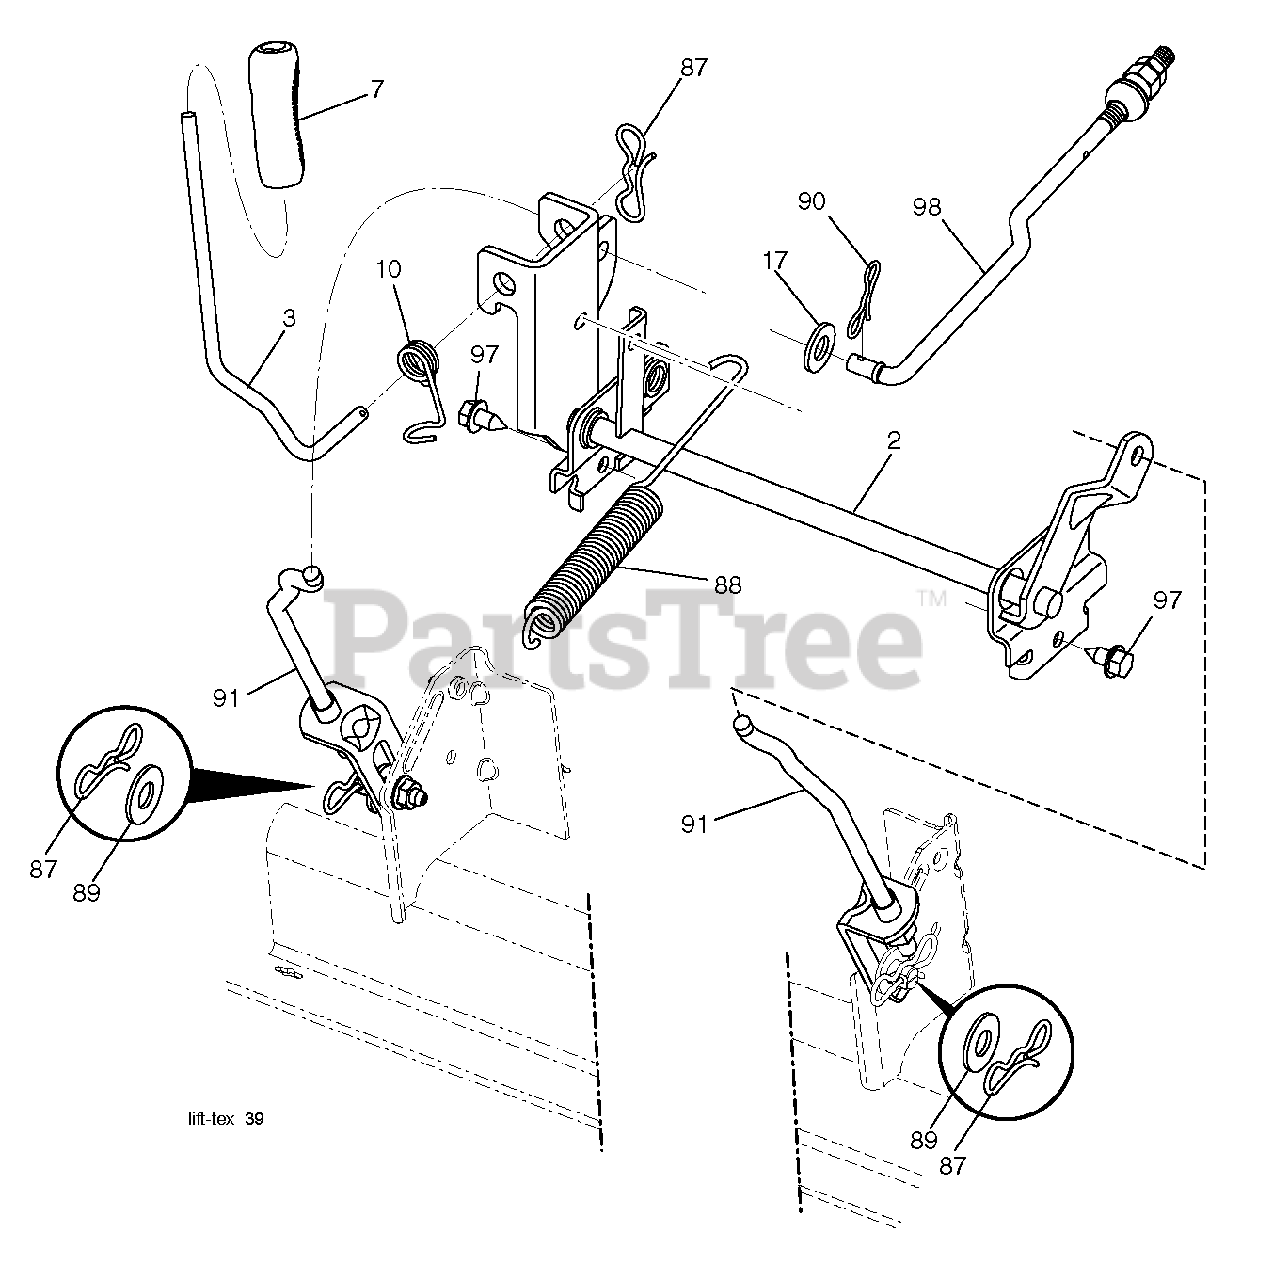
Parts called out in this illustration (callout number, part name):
2	SHAFT.ASM.CROSS.LIFT
3	LEVER.LIFT.HANDLE.LT
7	GRIP.HANDLE.LIFT.PVC.BLACK
10	SPRING.TORSION.LIFT.HANDLE
17	WASHER
87	PIN.COTTER.7/16.BOW TI.
88	SPRING.LIFT.ASSIST
89	WASHER.CLEAR.ZINC
90	PIN.COTTER.5/16.BOW TI
91	LINK.ASM.LIFT.REAR
97	SCREW, 3/8-16X3/4
98	LINK.ASM.SUSP.FRONT.MW
